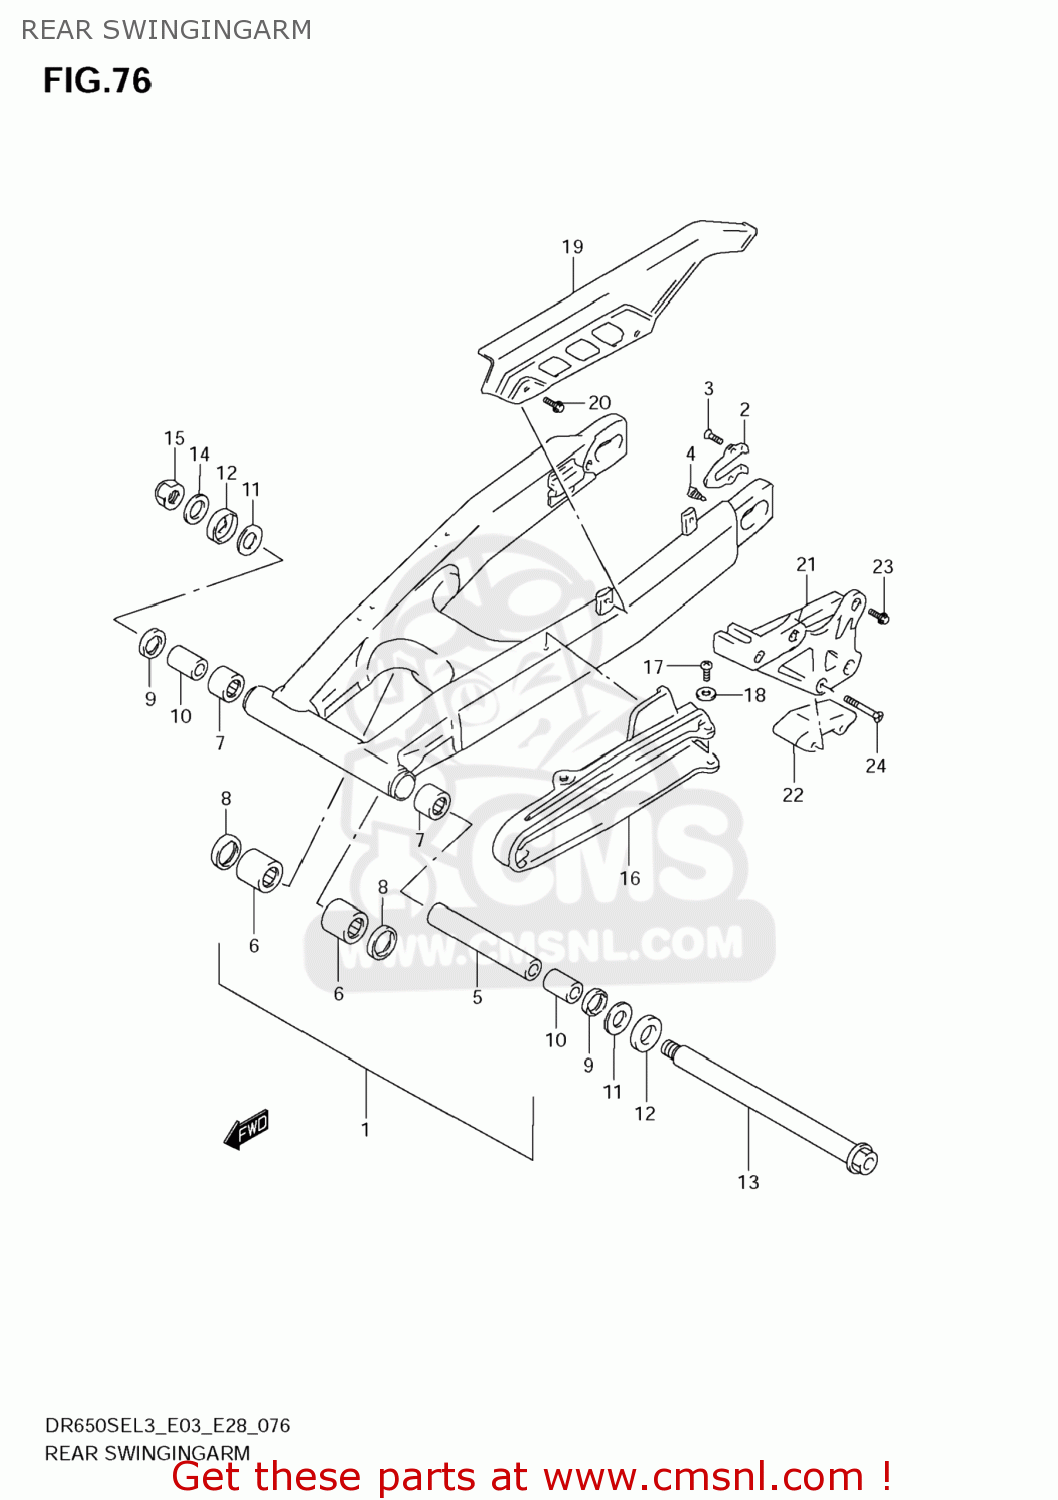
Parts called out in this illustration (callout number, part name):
1	SWINGINGARM ASSY,RR
2	PLATE,RR SWING ARM AXLE
3	SCREW(5X8)
4	STOPPER,CHAIN ADJUSTER
5	SPACER,SWGARM PIVOT CTR
6	BEARING(20X27X23.5)
7	BEARING(22X29X30)
8	SEAL,OIL(20X27X5)
9	SEAL,OIL(22X29X4)
10	SPACER,SWGARM PIVOT BRG
11	WASHER
12	COVER,SWINGINGARM PIVOT
13	AXLE,RR
14	WASHER
15	NUT
16	BUFFER,CHAIN TOUCH DEFENSE
17	SCREW
18	WASHER
19	CASE,CHAIN
20	BOLT(6X10)
21	GUIDE,CHAIN
22	DEFENSE,CHAIN GUIDE
23	BOLT
24	SCREW
